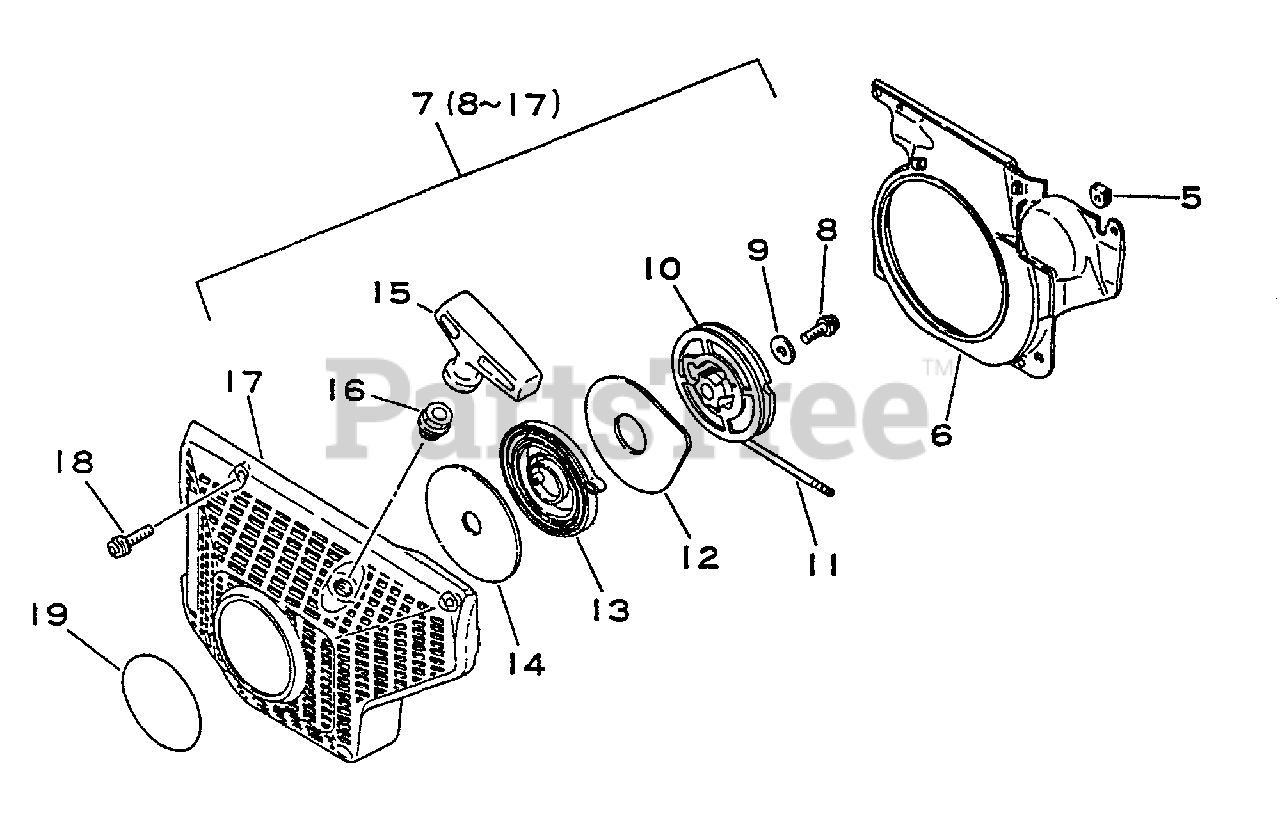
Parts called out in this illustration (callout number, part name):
6	SHIELD, FAN
7	STARTER ASSY
8	SCREW - 5X14
9	WASHER - 5
10	REEL, ROPE
11	ROPE, STARTER - 3.5X960
12	PLATE, STARTER
13	SPRING, REWIND
14	PLATE, STARTER
15	GRIP, STARTER
16	GUIDE, ROPE
17	CASE, STARTER
18	SCREW - 5X20
19	LABEL - ECHO
